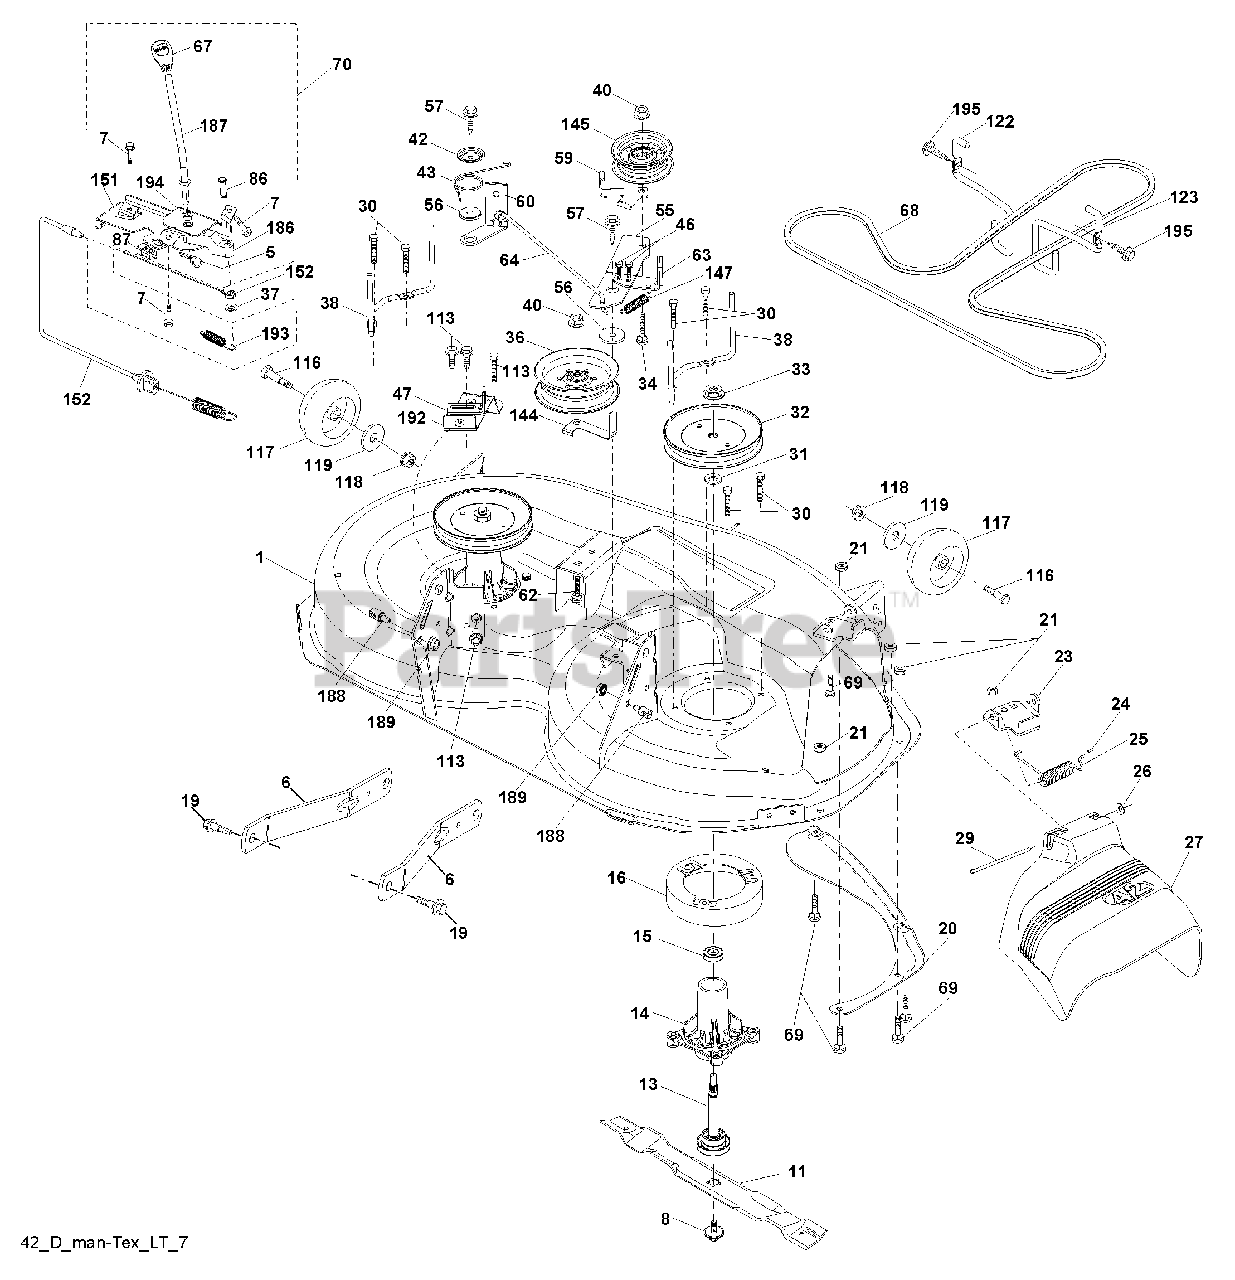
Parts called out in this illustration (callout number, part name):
5	Retainer Spring
6	Arm Suspension
7	Screw 10 x 3/4 Single Hex
8	Bolt/Washer asm 7/16-20 unf
8	Blade, 42" Mulching Premium (For better wear when mulching)
11	Blade, 42" Hi-Lift (For bagging or discharge)
11	Blade, 42" Mulching Std (For mulching mowers only)
13	Shaft Assembly, Mandrel
14	Housing, Mandrel
15	Bearing, Ball, Mandrel
16	Stripper, Mower Deck
19	Bolt, Shoulder
20	Baffle, Vortex
21	Nut, Crownlock 5/16-18 unc
23	Bracket, Deflector
24	Cap, Sleeve
25	Spring, Torsion, Deflector
26	Nut, Push
27	Shield, Deflector
29	Rod, Hinge
30	Screw Thdrol Rolling Wsh Hd
31	Washer, Spacer
32	Pulley, Mandrel
33	Nut, Toplock, Flanged
34	Bolt Carr Sh. 3/8-16 x 1-1/2 Gr. 5
36	Pulley, Idler, Flat
37	Washer 13/32 x 13/16 x 16 Ga.
38	Keeper Belt LH Mandrel
40	Nut, Lock Flg. 3/8-16 unc
42	Spring Torsion Brake
43	Spring Torsion Retainer
46	Screw Thd Roll 1/4-20 x 5/8
47	Bracket Clutch Cable
55	Arm, Idler
56	Spacer, Retainer
57	Screw Hexwsh Thd 3/8-16 x 1
59	Guard, Tuv Idler (94)
60	Arm Brake Mower
62	Bolt Rdhd Sqnk 3/8-16 unc x 2
63	Arm Brake Mower
64	Linkage Brake
67	Handle, Clutch Cable
68	V-Belt
69	Bolt Rdhd Sqnk 5/16-18 x 5/8
70	Clutch Asm. Manual
86	Pin Attachment Cable
87	Switch Interlock
113	Screw 5/16-18
116	Bolt
117	Wheel Gauge
118	Nut Lock 3/8-16 UNC
119	Washer 3/8-7/8 x 14 Ga.
122	Keeper Belt Eng. LH
123	Keeper Belt Eng. RH
144	Keeper Belt
145	Pulley Idler
147	Spring Return
151	Bracket Clutch CBL
152	Cable Clutch Manual w/Spr.
186	Arm Acutator CL Cable
187	Lever Control CL Cable
188	Stud Fastener
189	Nut Lock Hex Flange
192	Bracket Brake Stand LH
193	Spring Plunger Actuator
194	Bearing Control Lever Clutch
195	Screw Hexwsh Thdr 3/8-16 x 3/4
195	Mandrel Assembly
195	Replacement Mower, Complete
